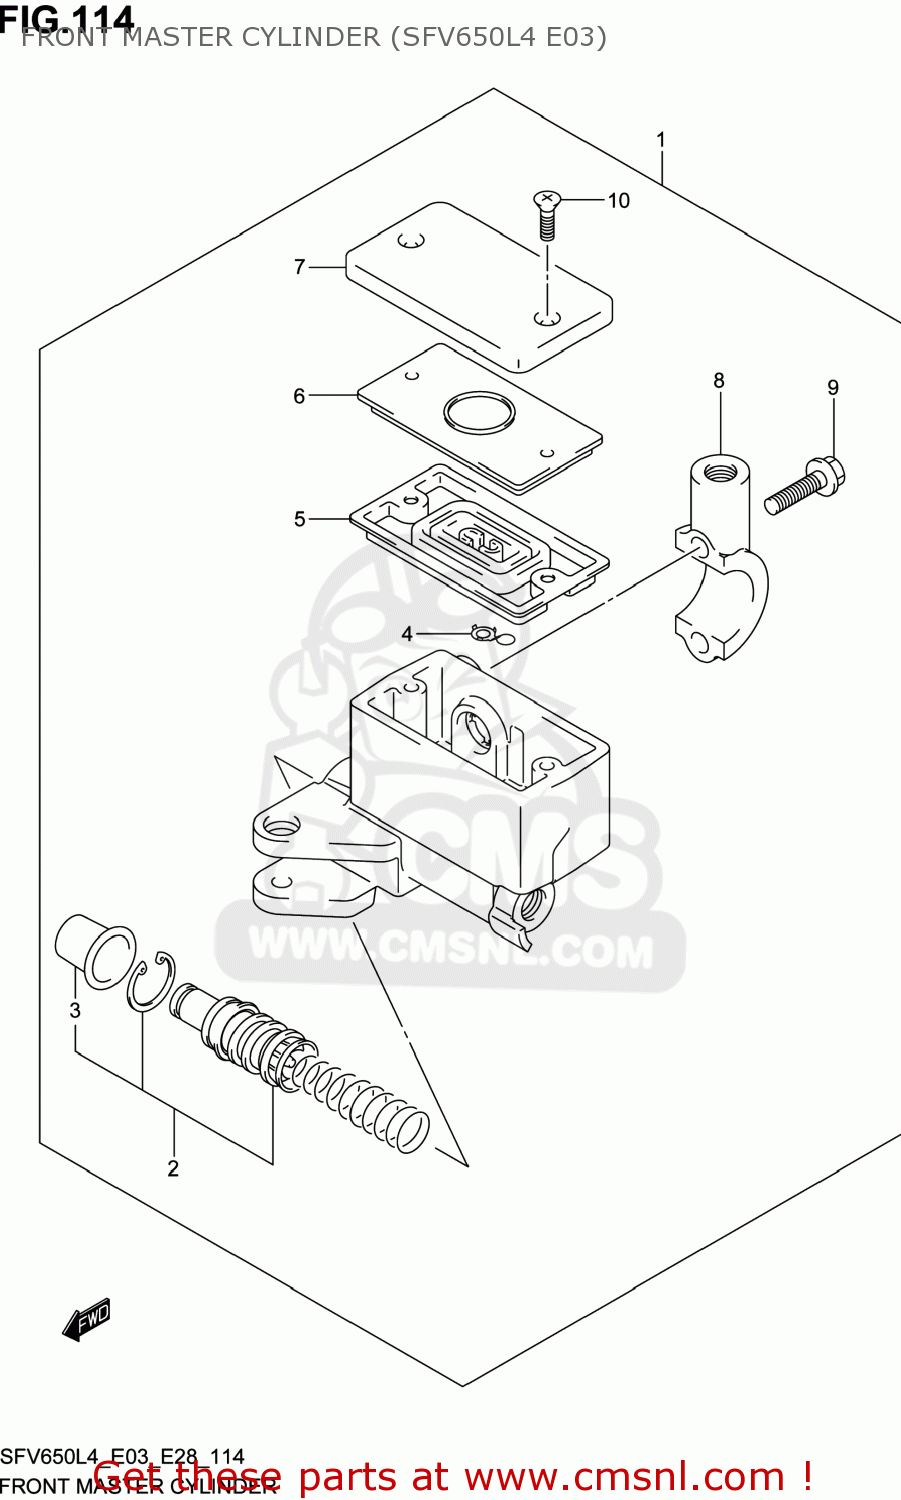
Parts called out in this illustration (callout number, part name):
1	CYLINDER ASSY,FR MASTER
2	PISTON & CUP SET
3	BOOT
4	PROTECTOR
5	6
6	PLATE,DIAPHRAGM
7	CAP
8	HOLDER
9	BOLT(6X22)
10	SCREW
